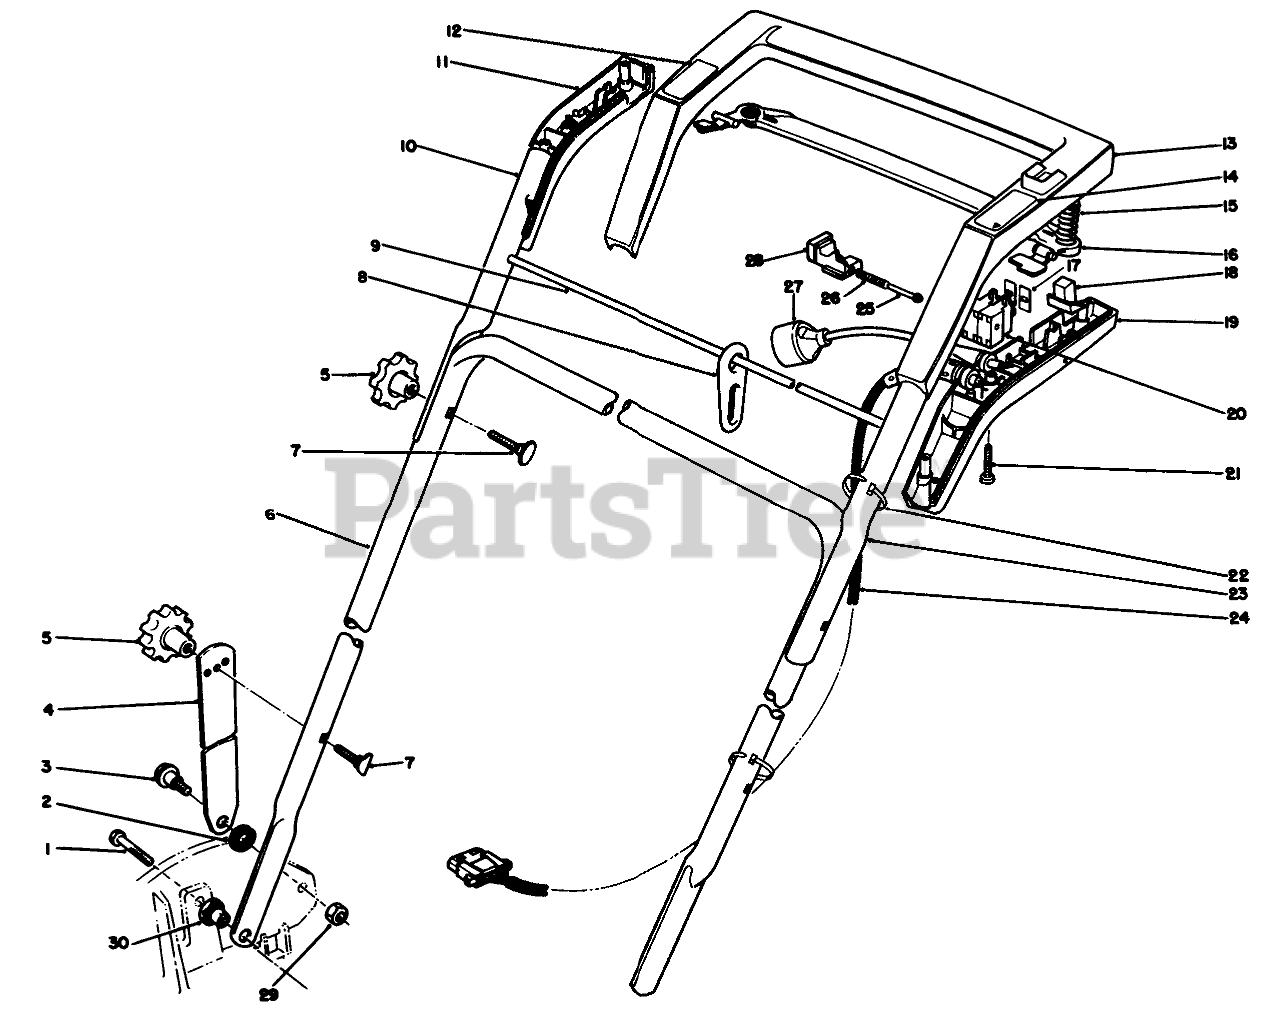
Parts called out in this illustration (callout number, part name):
1	SCREW-HH
2	SPACER
3	SCREW-SHOULDER
4	Handle Latch
6	LOWER HANDLE
7	5/16-18 X 2 HNDLE SCREW
8	CORD MINDER
9	CORD MINDER ROD
10	UPPER HDLE TUBE RH
11	RH GRIP COVER
12	DECAL - HANDLE, WARNING
13	Grip-Handle (Incl. Ref. #12 & 14)
14	ON/OFF DECAL
15	COMP SPRING
16	SQUEEZE LEVER
17	DUST COVER
18	SWITCH BUTTON
19	LH GRIP COVER
20	ON/OFF SWITCH
21	SCREW-PPH
22	Cable Tie
23	UPPER HDLE TUBE LH
24	WIRE HARNESS
25	BUTTON GUIDE
26	COMPRESSION SPRING
27	POWER SUPPLY CORD
28	INTERLOCK BUTTON
29	NUT-LOCK, NI
30	HANDLE PIVOT NUT
